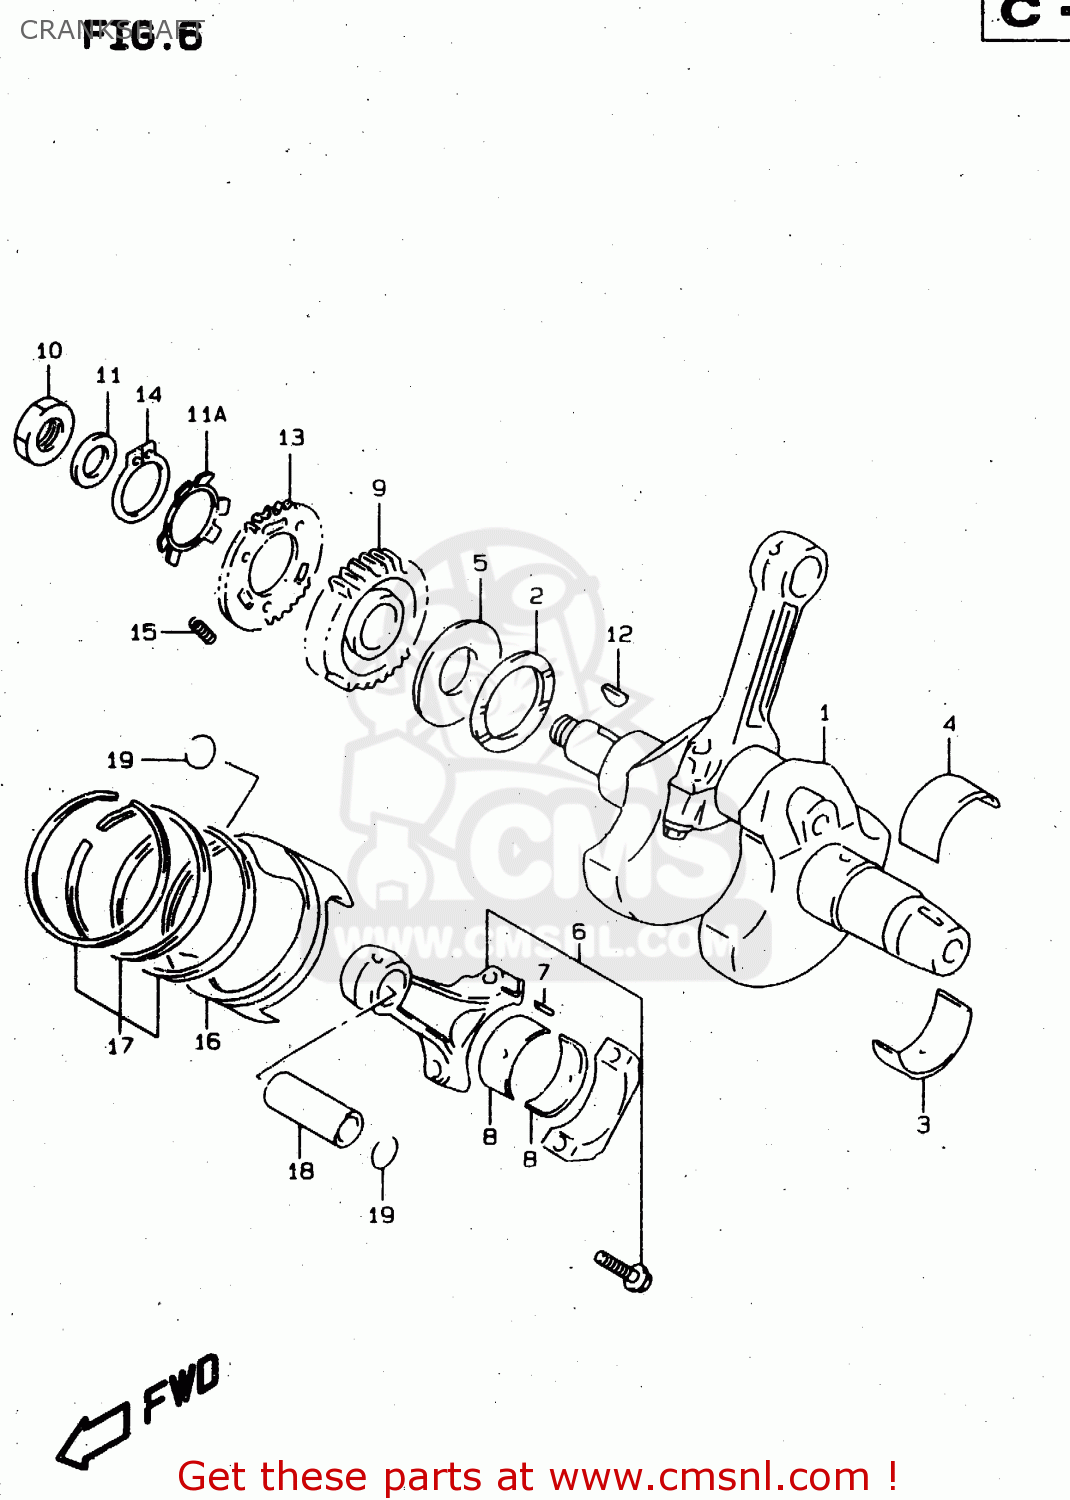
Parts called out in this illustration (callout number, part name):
1	CRANKSHAFT SET
2	WASHER(48.1X64X1.94)
3	BEARING,CRANKSHAFT
4	BEARING,CRANKSHAFT
5	WASHER,CRANK THRUST
6	CONNECTING ROD ASSY
7	PIN,CONNECTING ROD
8	BEARING,CRANK PIN
9	GEAR,PRIMARY DRIVE
10	NUT
11	WASHER
11A	WASHER,PRI DRIVE
12	KEY
13	GEAR,PRIMARY DRIVE SCISSORS
14	CIRCLIP
15	SPRING
16	PISTON
17	RING SET,PISTON
18	PIN,PISTON
19	CIRCLIP
